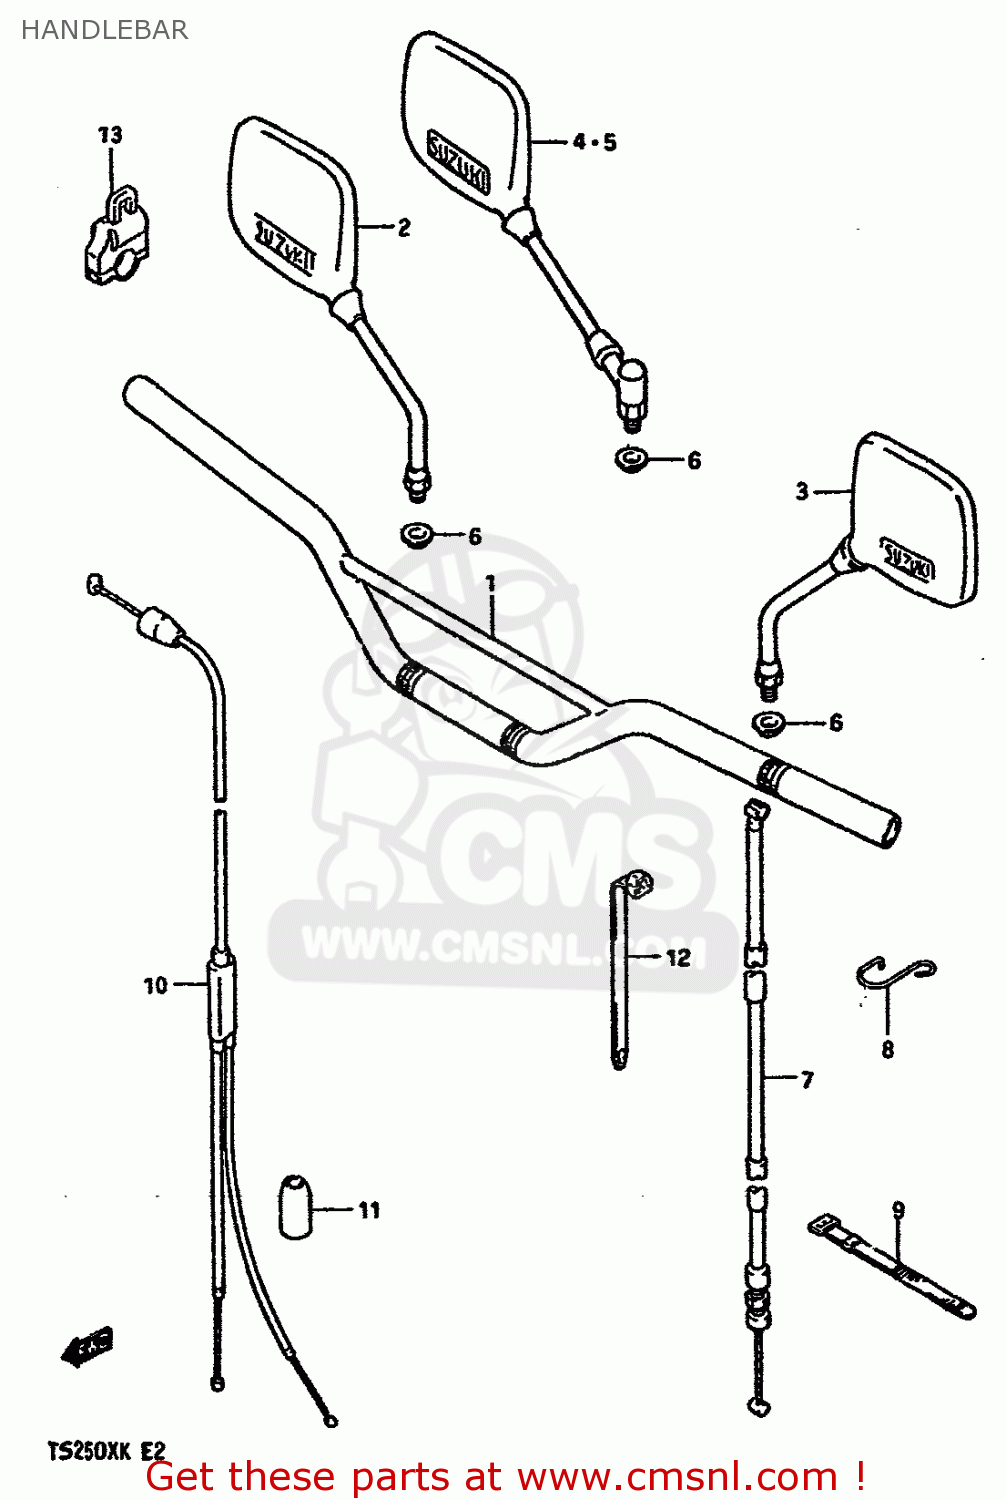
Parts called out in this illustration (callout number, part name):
1	HANDLEBAR (GOLD)
2	MIRROR ASSEMBLY,RIGHT
3	MIRROR ASSEMBLY,LEFT
4	MIRROR ASSY,REAR VIEW,RH
5	MIRROR ASSY,REAR VIEW,LH
6	WASHER,MIRROR STAY
7	CABLE ASSY,CLUTCH
8	GUIDE,CLUTCH CABLE
9	CLAMP
10	CABLE ASSY,THROTTLE
11	DUST SEAL
12	CLAMP(L:165)
13	LOCK ASSY,HELMET (GOLD)
